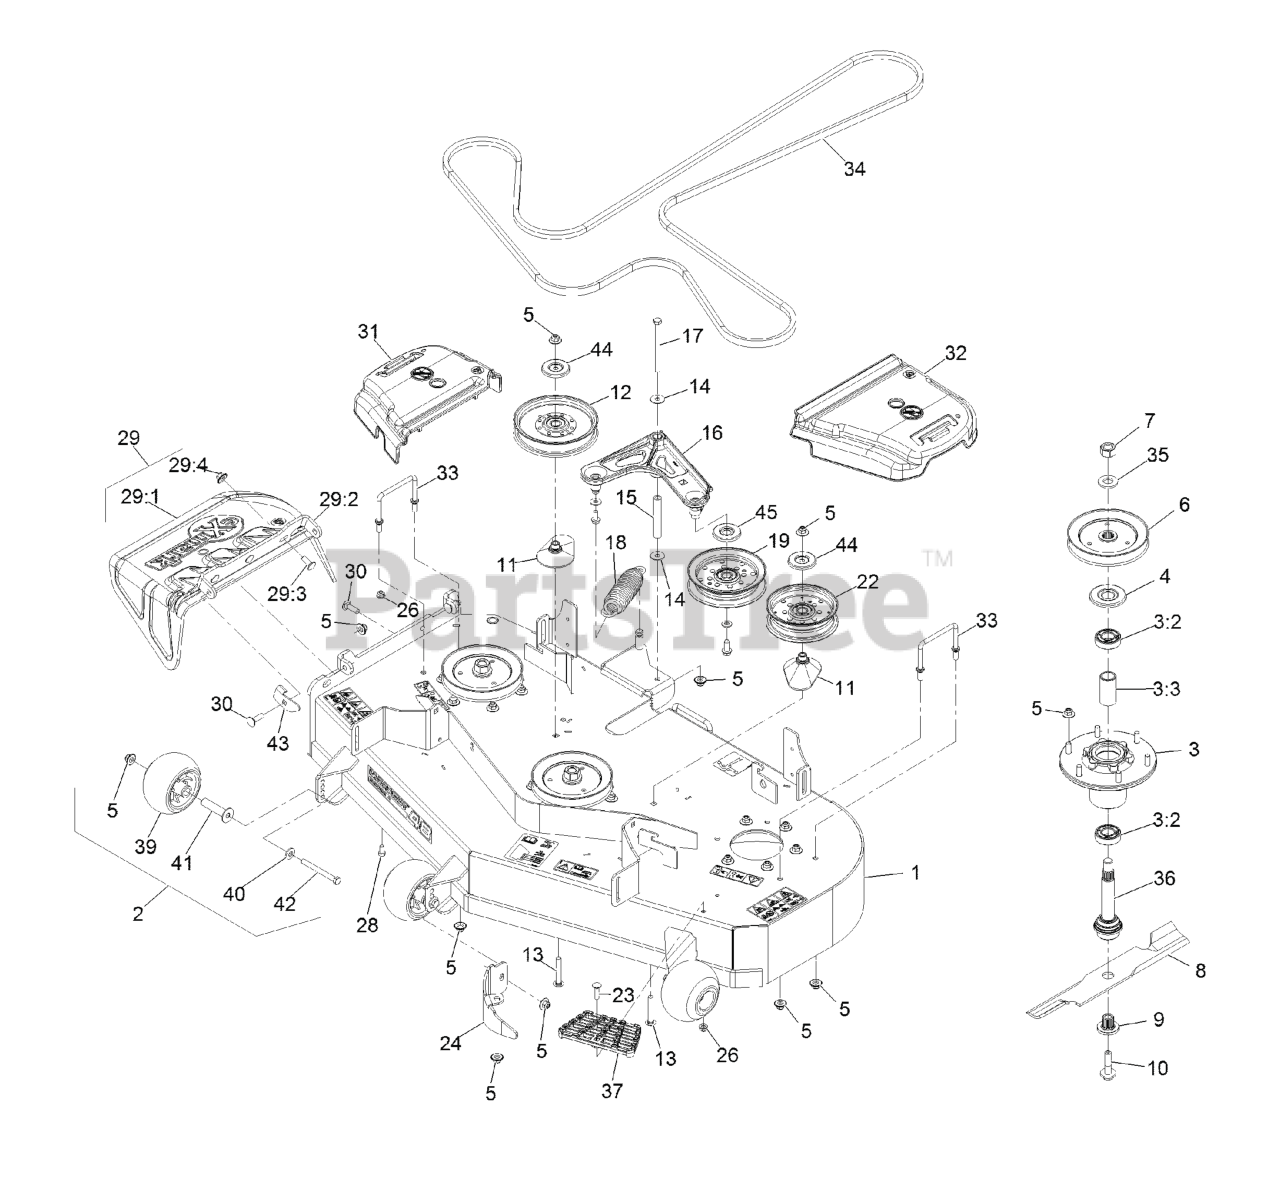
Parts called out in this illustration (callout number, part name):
1	ASM-DECK W/DECALS 484
2	KIT, ANTI-SCALP ROLLER
3	ASM-CUTTER HSG WITH BEARINGS
3:2	BEARING-BALL
3:3	SPACER-BEARING
4	GUARD,BEARING TOP .989
5	Nut-Nyloc 3/8-16 Flg
6	SHEAVE,BLADE DRIVE 5.90
7	NUT-HEX
9	BUSHING,SPLINED
10	SCREW,SEMS 1/2-20 X 2.19
11	SPACER-PULLEY
12	IDLER-PULLEY, FLAT 6.00X1
13	SCREW-CARR
15	BUSHING
16	IDLER ARM ASM
17	SCREW-HH
18	SPRING-EXTENSION
19	IDLER-PULLEY, FLAT
22	IDLER-PULLEY, FLAT 5.00X1
23	Bolt-Carriage 5/16-18 X 1 1/4
24	BAFFLE-DOGLEG,LZS LZX VT4
26	NUT-HF, NI
28	SCREW-HH
29	ASM,DISCHARGE CHUTE
29:1	CHUTE,DISCHARGE
29:2	BRACKET,DISCHARGE CHUTE
29:3	SCREW-CARR
29:4	Nut-Nyloc 3/8-16 Flg
30	BOLT-CARR
31	COVER-BELT, RH
32	COVER-BELT, LH
33	WIREFORM-COVER
34	BELT-V
36	ASM-SPINDLE AND SEAL
37	STEP-DECK
39	ROLLER-SCALP, ANTI
40	WASHER-BELLEVILLE
41	AXLE, ROLLER
42	SCREW-HH 3/8-16 X 3 3/4 GR 8
43	STOP-DISCHARGE CHUTE
44	SHIELD-DUST
45	SHIELD-GUARD, DUST
